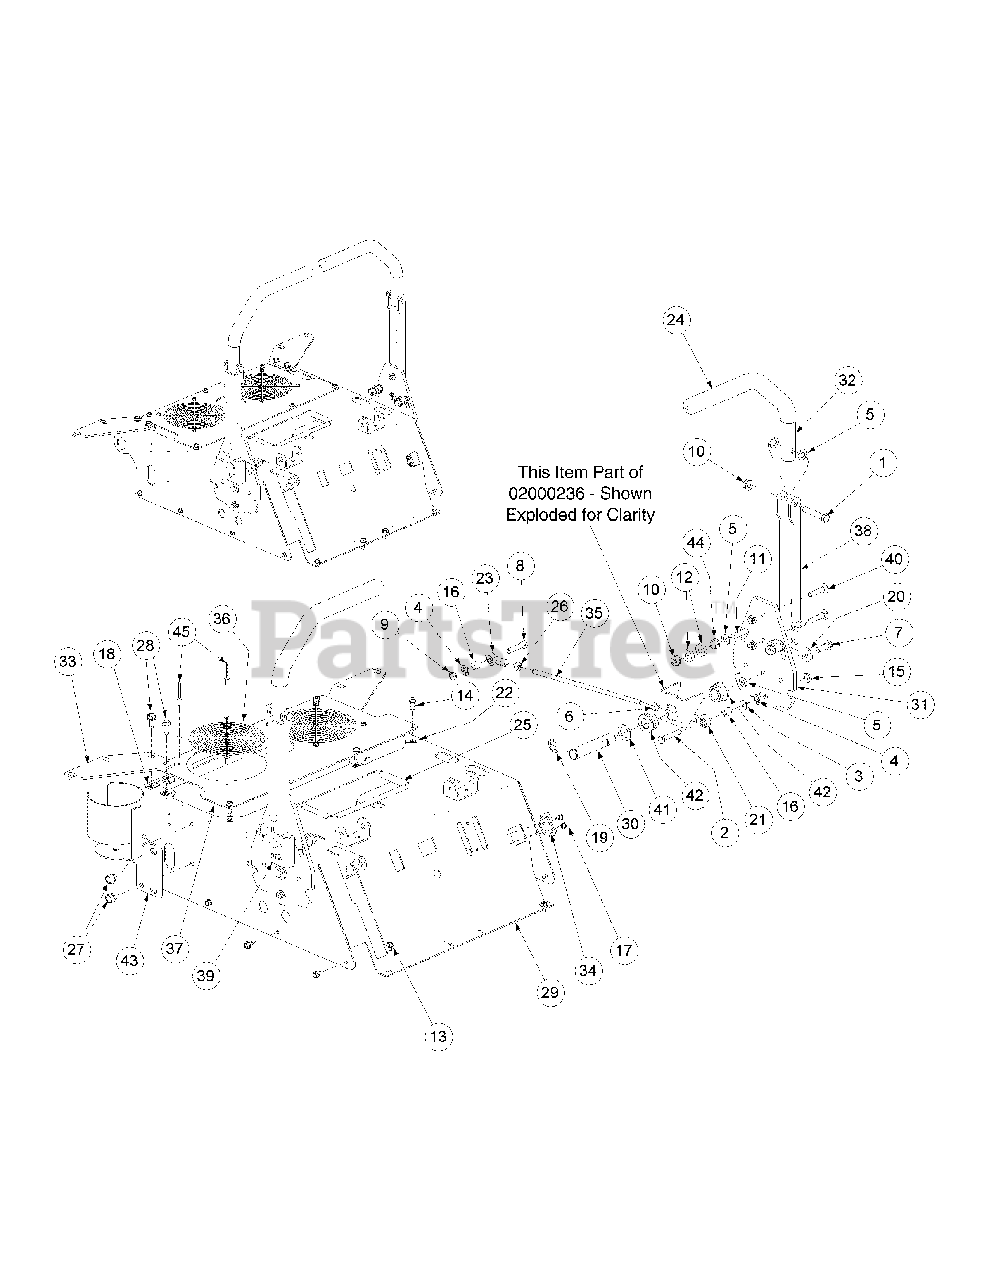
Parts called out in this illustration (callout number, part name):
1	Hex Cap Screw, 3/8-16 x 2
2	HHCS, 5/16-18, 1-3/4
3	Flat Washer, 5/16
4	Push Retainer, 5/16
6	Hex Nut, 5/16-24
7	Hex Cap Screw, 3/8-16 x 1.00
8	Hex Cap Screw, 5/16-18 x 1-1/2
9	Nut, 5/16-18, Center Lock
10	Flange Lock Hex Nut, 3/8-16
11	Carriage Screw 3/8-16 x 1.75
12	Spacer, Control Rod
13	Screw, TT, 1/4-20, 0.5, Hex Index Washer
14	Screw, TT, 1/4-20, 0.75, Hex Index Washer
15	Nut, Lock, HexFlange, 5/16-18
16	Spacer, .265 x .500 x .562
17	Screw, TT, 10-24, .5
18	U-Nut, 5/16-18
19	E Clip, 3/4 Dia.
20	Flat Washer, .385 ID x 1.00 OD x .145
21	Rod End, 5/16, Right Hand
22	U-Nut, 1/4-20
23	Rod End, 5/16, Left Hand
24	Lap Bar Grip
25	Battery Edge Trim
26	Hex Nut, 5/16-24, Left Hand
27	Self Tapping Screw, 5/16-18 x 1/2
28	Hex Washer Screw 5/16-18 x .750
29	Control Housing Assembly
30	Steering Input Shaft
31	Steering Pivot Plate
32	Pivot Handle Control Tube
33	Tank Front Mounting Plate
34	Brake Switch Mounting Bracket
35	Steering Link Rod
36	Fan Cover
37	Hydro Service PLate
38	Lapbar Pivot Bracket, LH
39	Lapbar Pivot Bracket, RH
40	Carriage Bolt, 5/16-18 x 1.50
41	Flat Washer, 1.125 ID x .75 OD x .005
42	Hex Flange Bearing, .752 ID
43	Cup Holder Assembly
44	Hex Nut, 3/8-16
45	Screw, TT, 10-24, .5
